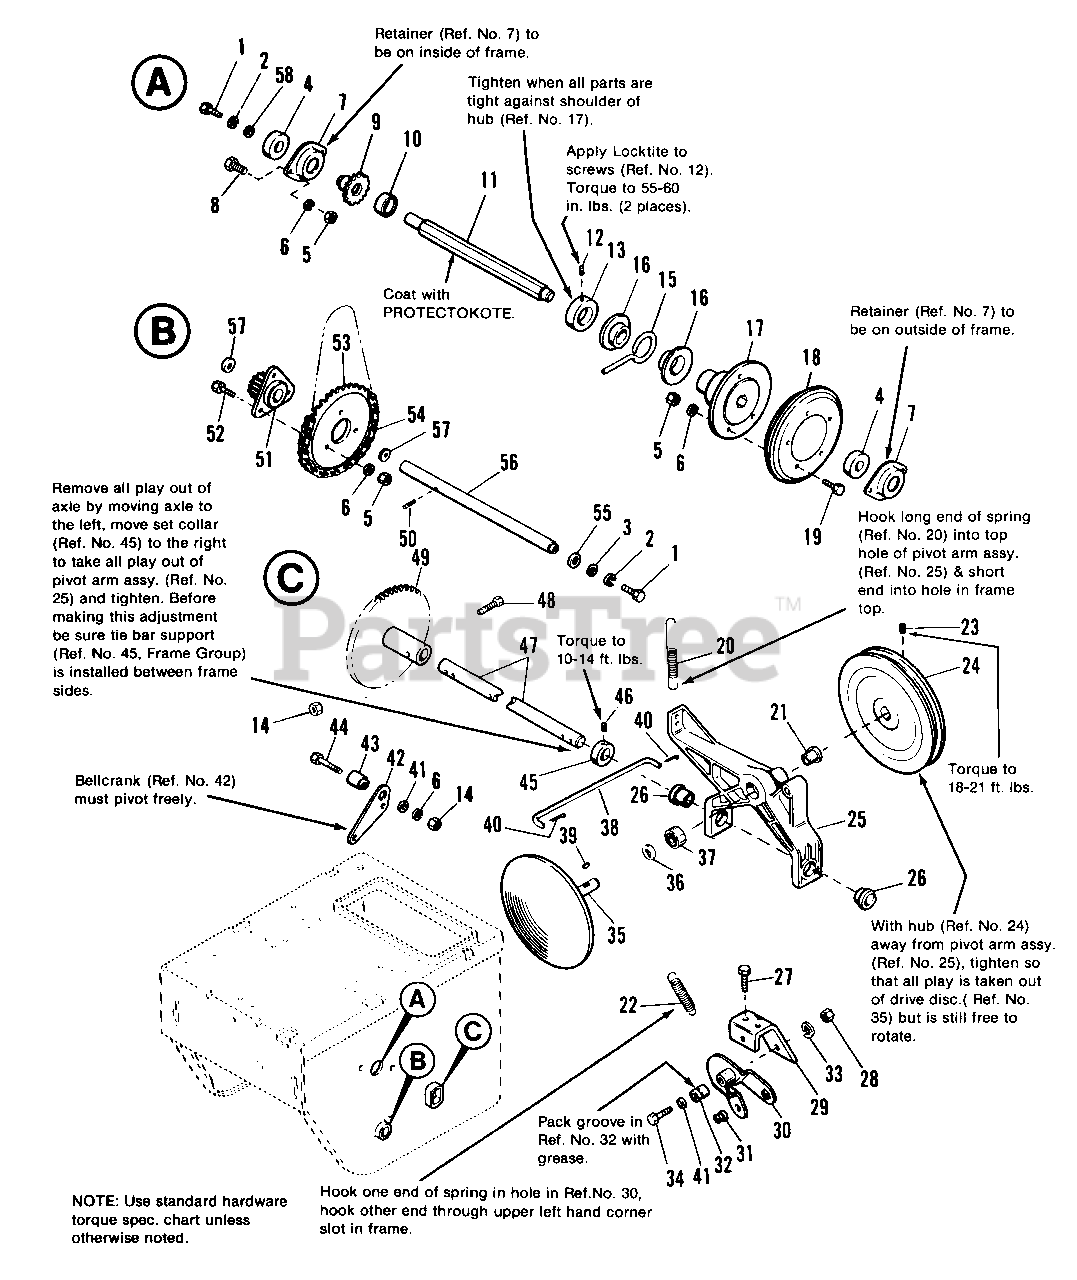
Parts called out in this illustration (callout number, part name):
1	CAPSCREW, Hex Hd., 1/4-20 x 5/8
2	LOCKWASHER, 1/4
3	WASHER, Flat, 1/4
5	NUT, Hex, 5/16-18
6	LOCKWASHER, 5/16
7	RETAINER, Bearing
8	CAPSCREW, Hex Hd., 5/16-18 x 5/8
9	SPROCKET, 10 Tooth
12	SETSCREW, Socket Hd., 1/4-20 x 3/8
14	NUT, Hex, Lock, 5/16-18
16	COLLAR, Thrust
17	HUB, Friction Disc
18	DISC, Friction
19	CAPSCREW, Hex Hd., 5/16-18 x 3/4
22	SPRING
23	SETSCREW, Sq. Hd., 5/16-18 x 1/2
24	PULLEY, Traction
25	ARM ASSY., Pivot w/Bushings
27	SCREW, Taptite, 5/16-18 x 1/2
28	NUT, Hex, 3/8-16
29	BRACKET, Bushing
30	ARM ASSY., Shift w/Bushings (Includes Ref. No. 31)
31	BUSHING, Ball
32	BUSHING, Spacer
33	LOCKWASHER, 3/8
34	CAPSCREW, Hex Hd., 3/8-16 x 2
35	DISC, Drive
39	KEY, Woodruff, 3/16 x 5/8
40	PIN, Cotter, 1/8 x 3/4
41	WASHER, Flat, 5/16
43	BUSHING, Pivot
44	CAPSCREW, Hex Hd., 5/16-18 x 2-1/4
45	SET COLLAR
46	SETSCREW, Sq. Hd., 5/16-18 x 1/2
48	CAPSCREW, Hex Hd., 5/16-18 x 1-1/2
50	PIN, Roll, 1/8 x 1
52	CAPSCREW, Hex Hd., 5/16-18 x 1
53	SPROCKET, 36 Tooth
54	CHAIN, Drive
55	WASHER, Int. Lock 1/2
58	WASHER, Flat, 1/4
